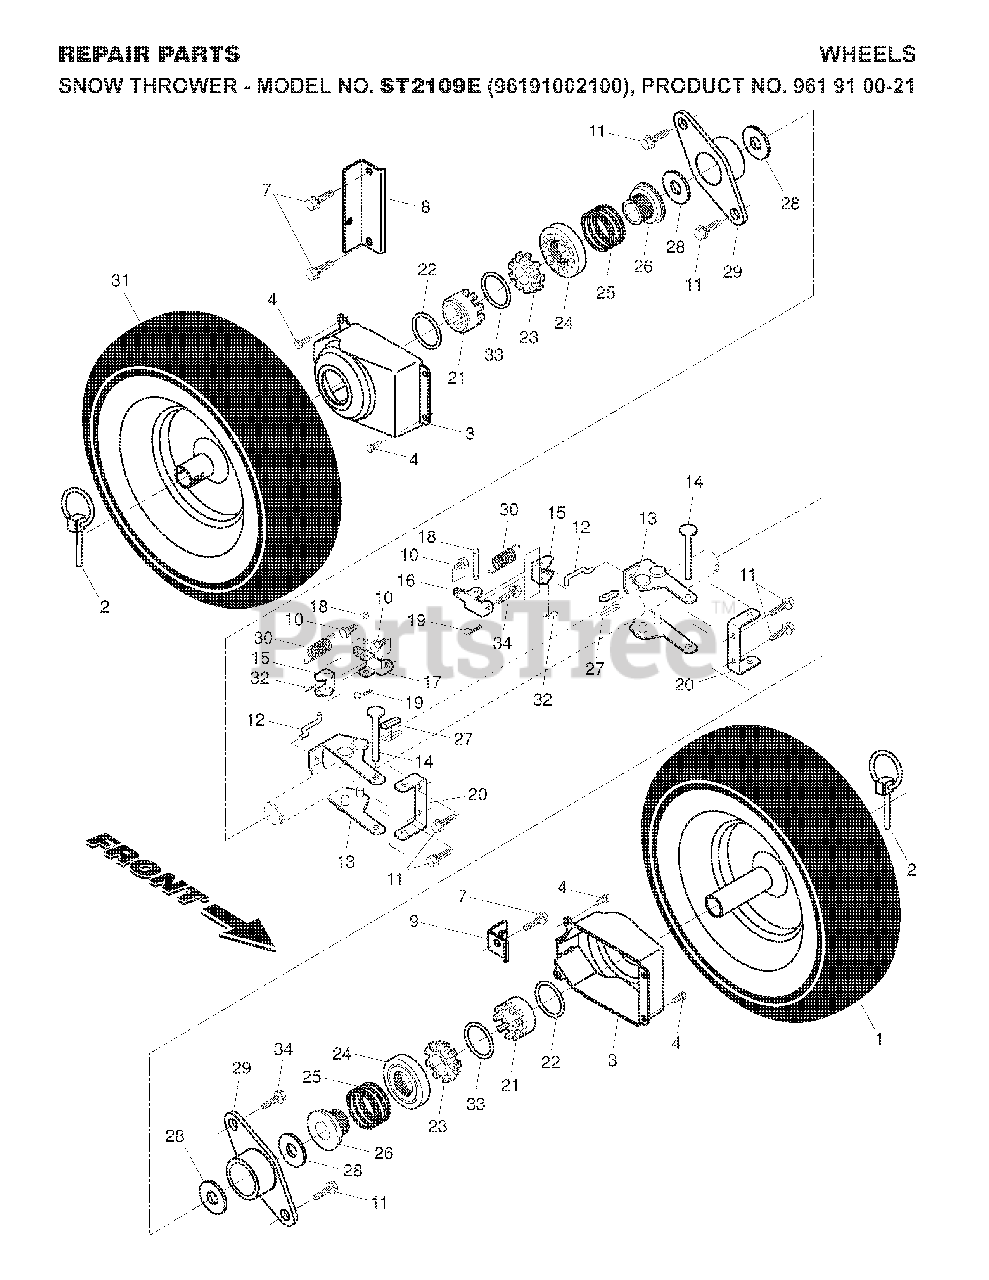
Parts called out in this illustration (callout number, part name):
1	16 X 4.8 LH WHEEL GREY
2	PIN KLIK, 1/4
3	COVER, POWER STEERING
4	SCREW, HEX HEAD, TAPPING
7	SCREW 3/8-16X1
8	BRACKET, STEERING CABLE RH
9	BRACKET.STEER.CABLE.LH.BZP
12	LINK.STEER.YOKE
13	STEERING YOKE
14	PIN, STEERING LEVER
15	BELLCRANK.STEER
16	CONTROL SHAFT
17	BRKT.STEER.PIVOT.RH
18	PIN, STEERING BELLCRANK
19	RETAINER CLIP PM
20	BRACKET.STEER.PNT.BLACK
21	DRIVER WHEEL
22	RING, WIRE RETAINER
23	LOBE WHEEL
24	SLIDE.CLUTCH
25	SPRING, CLUTCH SLIDE
26	LOBE.AXLE
27	KEY, SQUARE 1/4 X .875
28	WASHER TRUST 1"
29	BEARING, AXLE
30	SPRING LATCH
31	16 X 4.8 RH WHEEL
32	RETAINER CLIP
